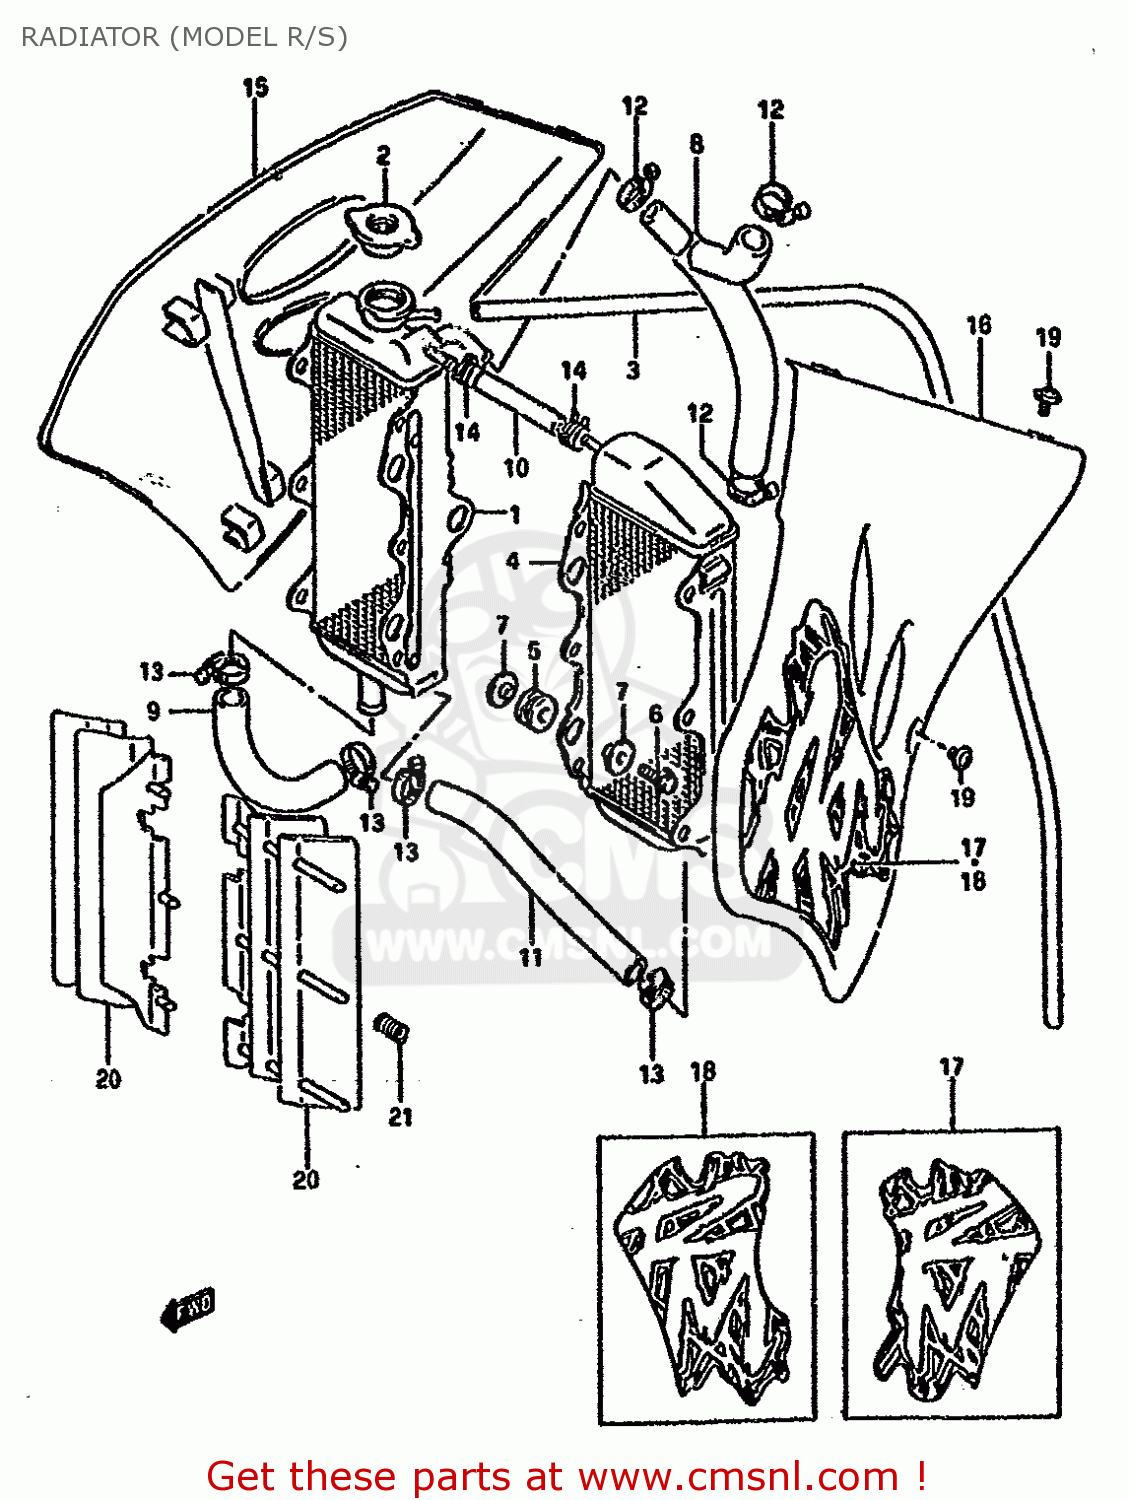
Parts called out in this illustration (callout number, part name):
1	RADIATOR ASSEMBLY,WATER
2	CAP,RADIATOR
3	HOSE(5X8X2000)
4	RADIATOR,WATER,L
5	CUSHION,RADIATOR LWR
6	SCREW
7	WASHER,RDTR SPRT
8	HOSE,RADIATOR INLET
9	HOSE,RADIATOR OUTLET
10	HOSE,WATER
11	HOSE,RADIATOR JOINT
12	CLAMP
13	CLAMP
14	CLIP
15	COVER,RADIATOR
16	COVER,RADIATOR
17	EMBLEM,RADIATOR COVER
18	EMBLEM,RADIATOR COVER
19	SCREW(6X12)
20	LOUVER,RADIATOR
21	SPRING
22	SPRING
23	CUSHION,RADIATOR COVER
